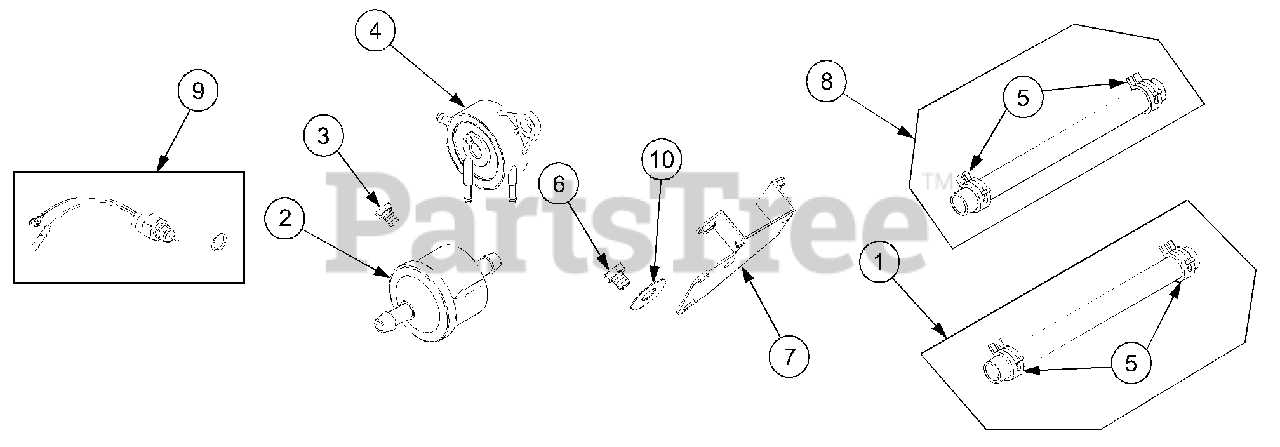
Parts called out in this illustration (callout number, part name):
1	Line, Fuel
2	Filter, Fuel
3	Screw, Fuel Pump
4	Pump, Fuel
5	Clamp, Hose
6	Screw, Fuel Pump Bracket
7	Bracket, Fuel Pump
8	Hose, Vacuum
9	Solenoid, Fuel
